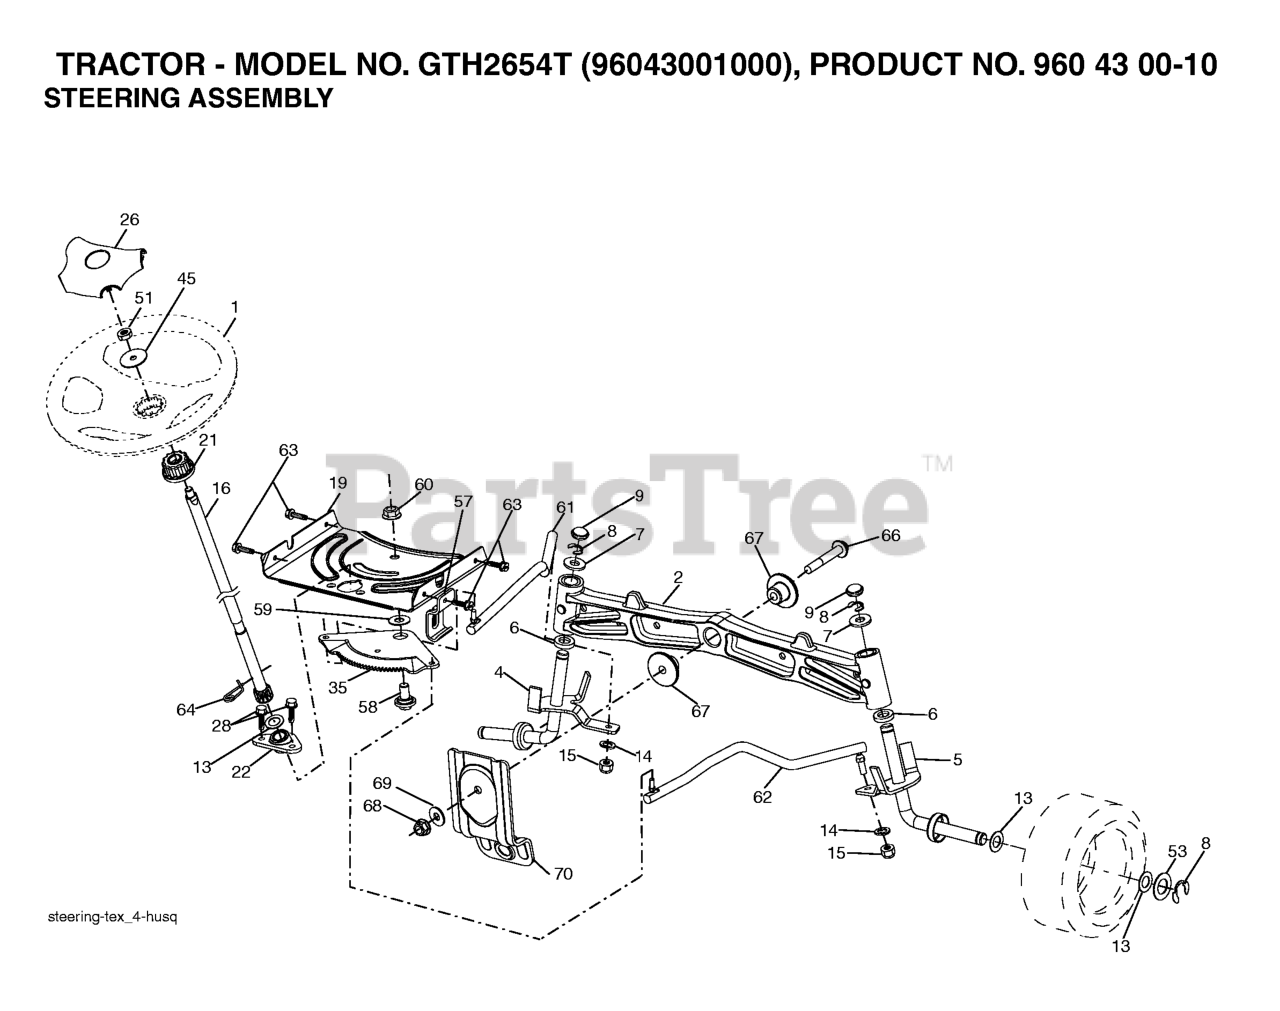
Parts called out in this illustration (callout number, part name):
1	WHEEL.STEERING.LEGEND2.GRY
2	AXLE.CAST.IRON
4	SPINDLE.ASM.LH.DDL.GT
5	SPINDLE.ASM.RH.DDL.GT
6	THRUST WASHER
9	CAP.SPINDLE.BLACK
14	WASHER, LOCK 3/8
15	NUT CROWNLOCK 3/8-24
16	SHAFT.STEER.STEALTH.DD
19	PLATE.STEER.DDL.NLT/NG
21	ADAPTER, WHEEL STNG..
22	BUSHING.ASM.STEERING.A
26	INSERT.CAP.STRG.WH.GRAY
28	SCREW, 3/8-16X3/4
35	GEAR.SECTOR.PLATE.DDL.
45	WASHER 9/16"ID, 2 3/8"OD
51	NUT.HEX.1/2-20
53	WASHER.HARDENED
57	BRKT.UPSTOP.GT/LT.TEX
58	BOLT.SHOULDER.SECTOR.P
59	WASHER.THURST.SECTOR.S
60	NUT FLANGE LOCK 5/8-11
61	DRAGLINK.LH.BALLSTUD.D
62	DRAGLINK.RH.BALLSTUD.D
63	SCREW
64	RETAINER.CLIP.SPRING.S
66	BOLT HEX FGHD 7/16-14 X 3 SERR
67	BUSHING.PM.FRONT AXLE
68	NUT.LOCK.FLANGE.7/16
69	WASHER.1.5X.505X.118
70	BRKT.DECK.SUSPENSION.F
